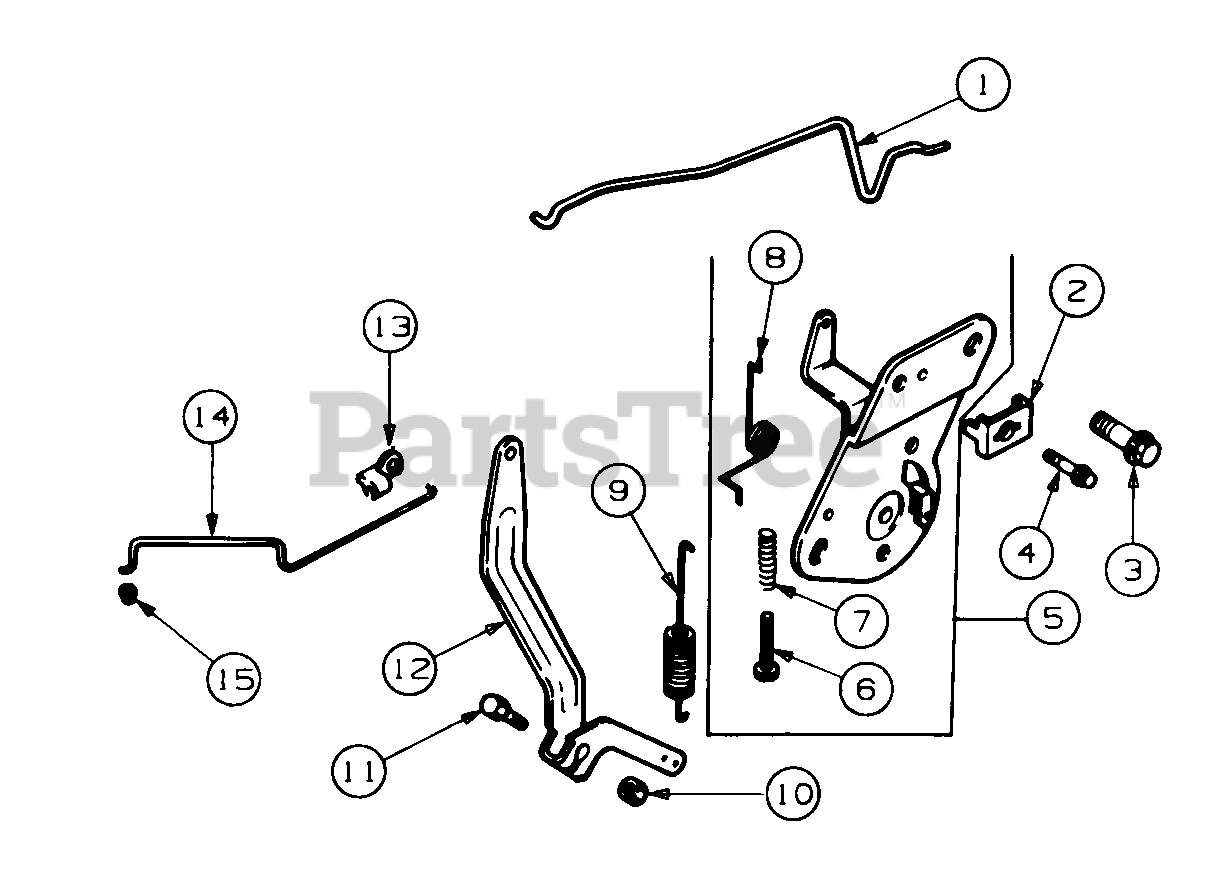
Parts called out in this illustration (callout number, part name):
1	Linkage, Choke
2	Clamp, Cable
3	Screw, Cable Clamp
4	Screw, Hex Hd, M6 X 1.0 X 16
5	Control, Speed Assy (Includes Ref No. 6 thru 8)
7	Spring, Speed Control
8	Spring, Choke Return
9	Spring, Governor
10	Nut, Governor Arm, M6 X 1.0
11	Screw, Governor Arm, M6 X 1.0 X 25
12	Lever, Governor
14	Linkage, Throttle
